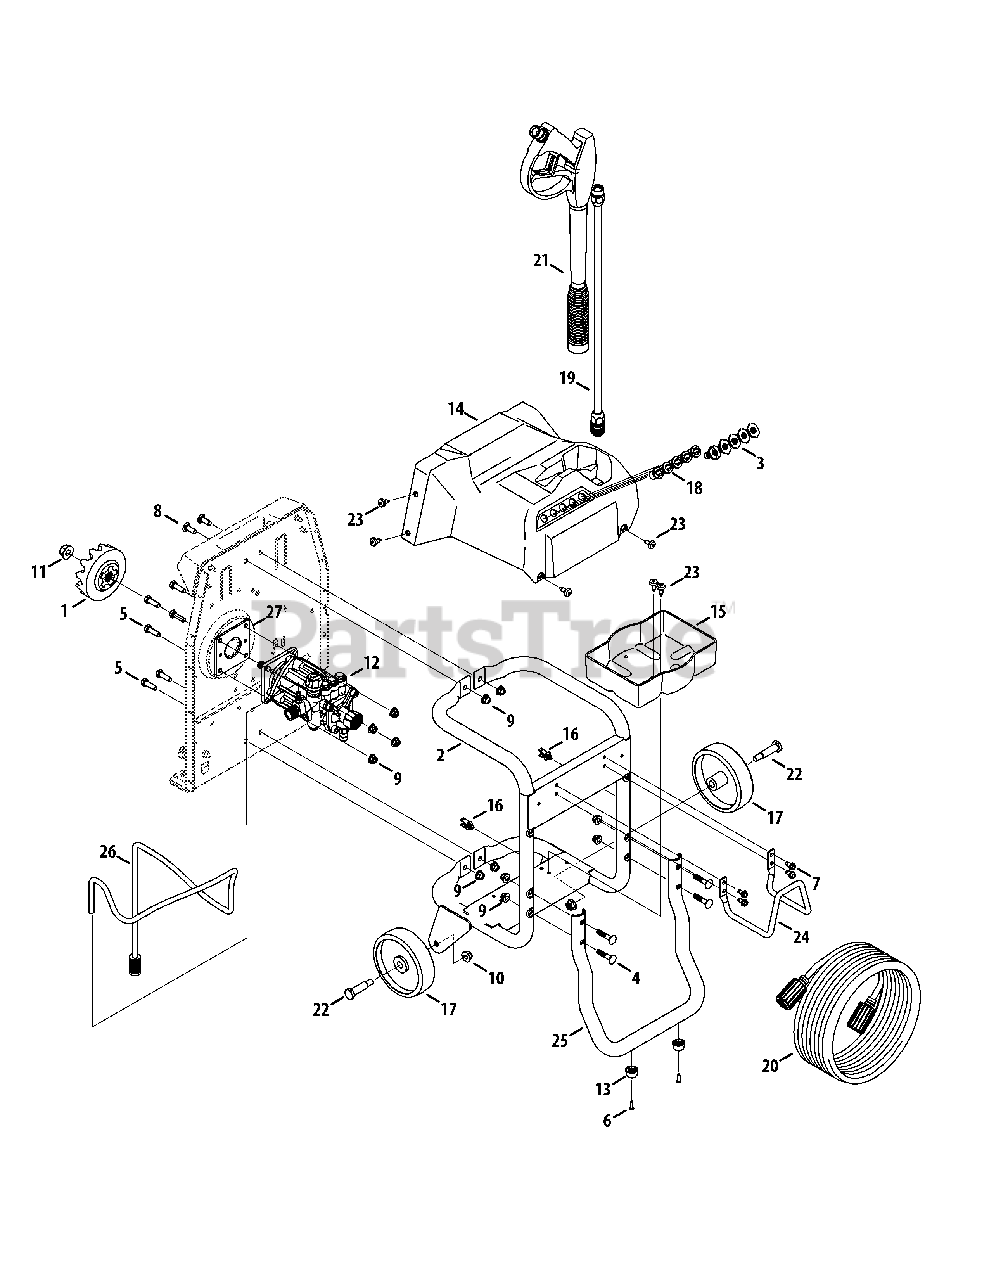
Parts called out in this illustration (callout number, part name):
1	Clutch Assembly
2	Frame Assembly
3	Nozzle Fitting Assembly
4	Carriage Bolt, 5/16-18 x 1.50
5	Hex Cap Screw, 5/16-18 x 1.00
6	Screw, 8-32 x .625
7	Hex Washer Screw, 1/4-20 x .500
8	Bolt, Carriage, 5/16-18 x .875
9	Flange Lock Nut, 5/16-18
10	Flange Lock Nut, 3/8-16
11	Flange Lock Nut, 1/2-13
12	Pump
14	Power Wash Cover
15	Soap Retainer Tray
17	Deck Wheel, 5.0 x 1.38
18	Grommet, .45 ID x .81 OD x .83
19	Extension Tube
20	Hose, .25 ID x 40ft
21	Control Handle
22	Shoulder Bolt, .496 x 1.525
23	Shoulder Screw, 1/4-20
24	Hose Hanger Rod
26	Soap Inlet Tube
27	Pump Adaptor Mounting Plate
